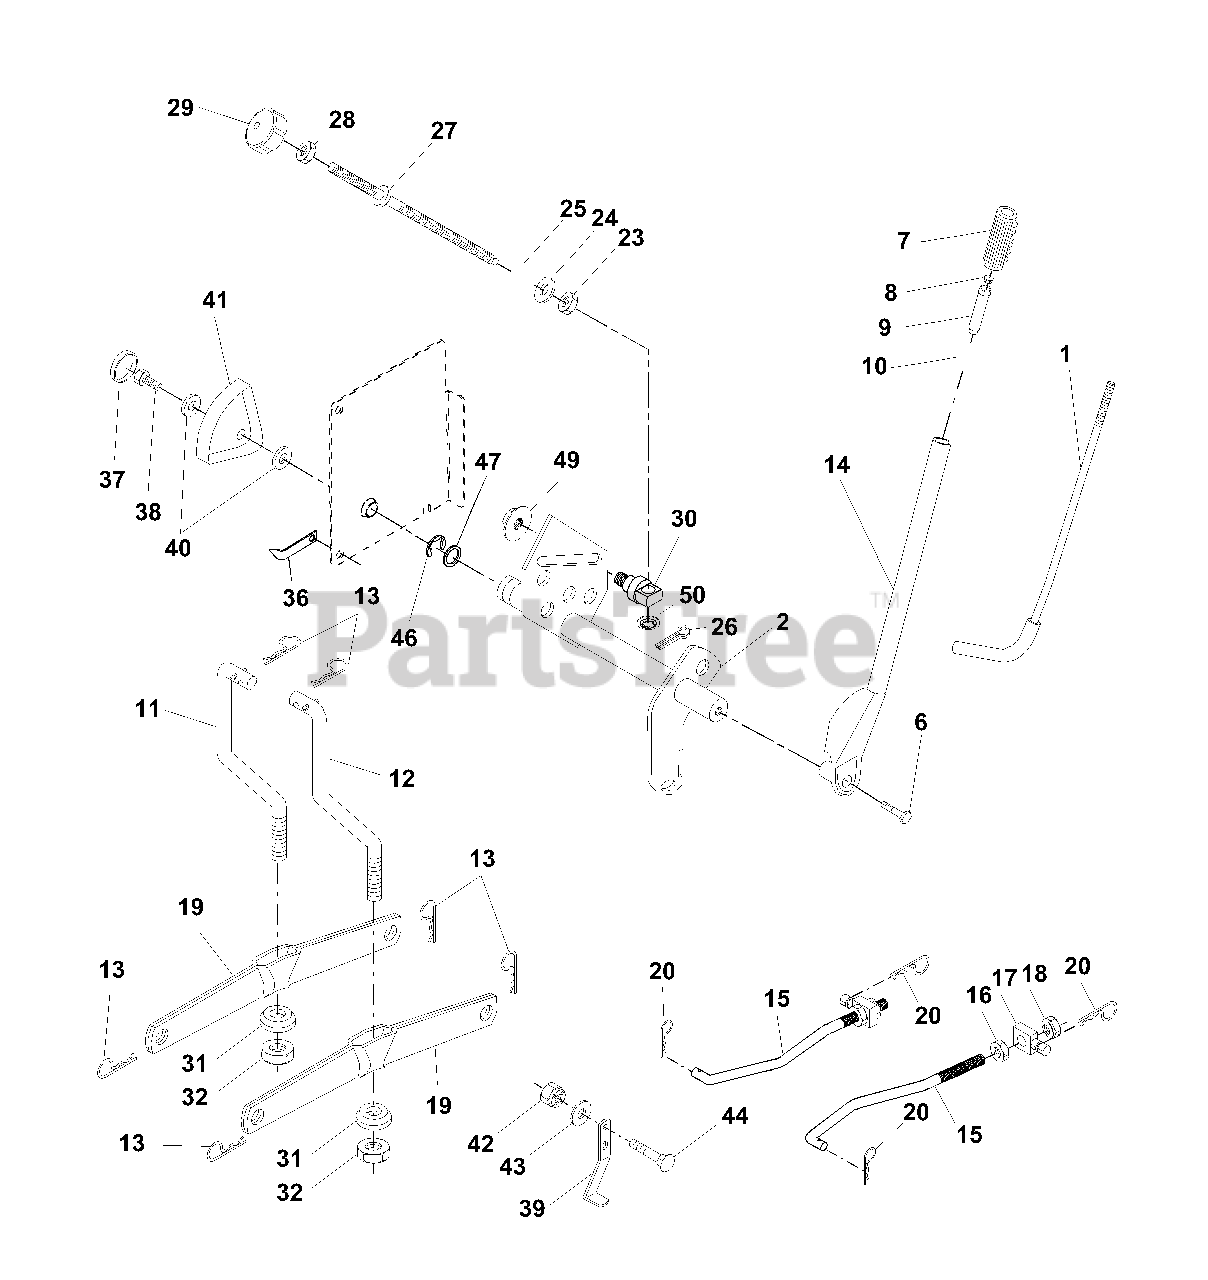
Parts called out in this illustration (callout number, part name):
1	Rod Assembly, Lever
2	Shaft Assembly, Lift
6	Bolt, Hex Head, Fin. 3/8-16 x 1-1/2
7	Grip Handle
8	Button Plunger Black
9	Plunger Lever Lift
10	Spring
11	Link, Lift, LH
12	Link, Lift, RH
13	Retainer Spring
14	Lever Assembly, Lift, RH
15	Link, Front
16	Nut, Hex, Jam 1/2-13 UNC
17	Trunnion
18	Nut Lock W/Wsh 1/2-13 Unc
19	Arm, Suspension, Rear
20	Retainer Spring
23	Nut Special
24	Washer 13/32 x 5/8 x 16 Ga.
25	Spring Compression
26	Pin Cotter
27	Rod Adj. Lift
28	Nut Hex Jam 3/8-16 Unc
29	Knob Inf. 3/8-16 Unc
30	Trunnion Infin Height
31	Bearing
32	Nut, Crownlock 3/8-24
36	Pointer Height Indicator
37	Plug Hole
38	Screw 5/16-18 x 1
39	Stop Over Center
40	Washer 11/32 x 1-1/2 10 Ga.
41	Scale Ind. Height
42	Nut, Crownlock 3/8-16 UNC
43	Washer 13/32 x 1 x 12 Ga.
44	Bolt, Carriage 3/8-16 x 1.00
46	E-Ring
47	Washer
49	Nut Hex Flange Lock
50	Nut Push
